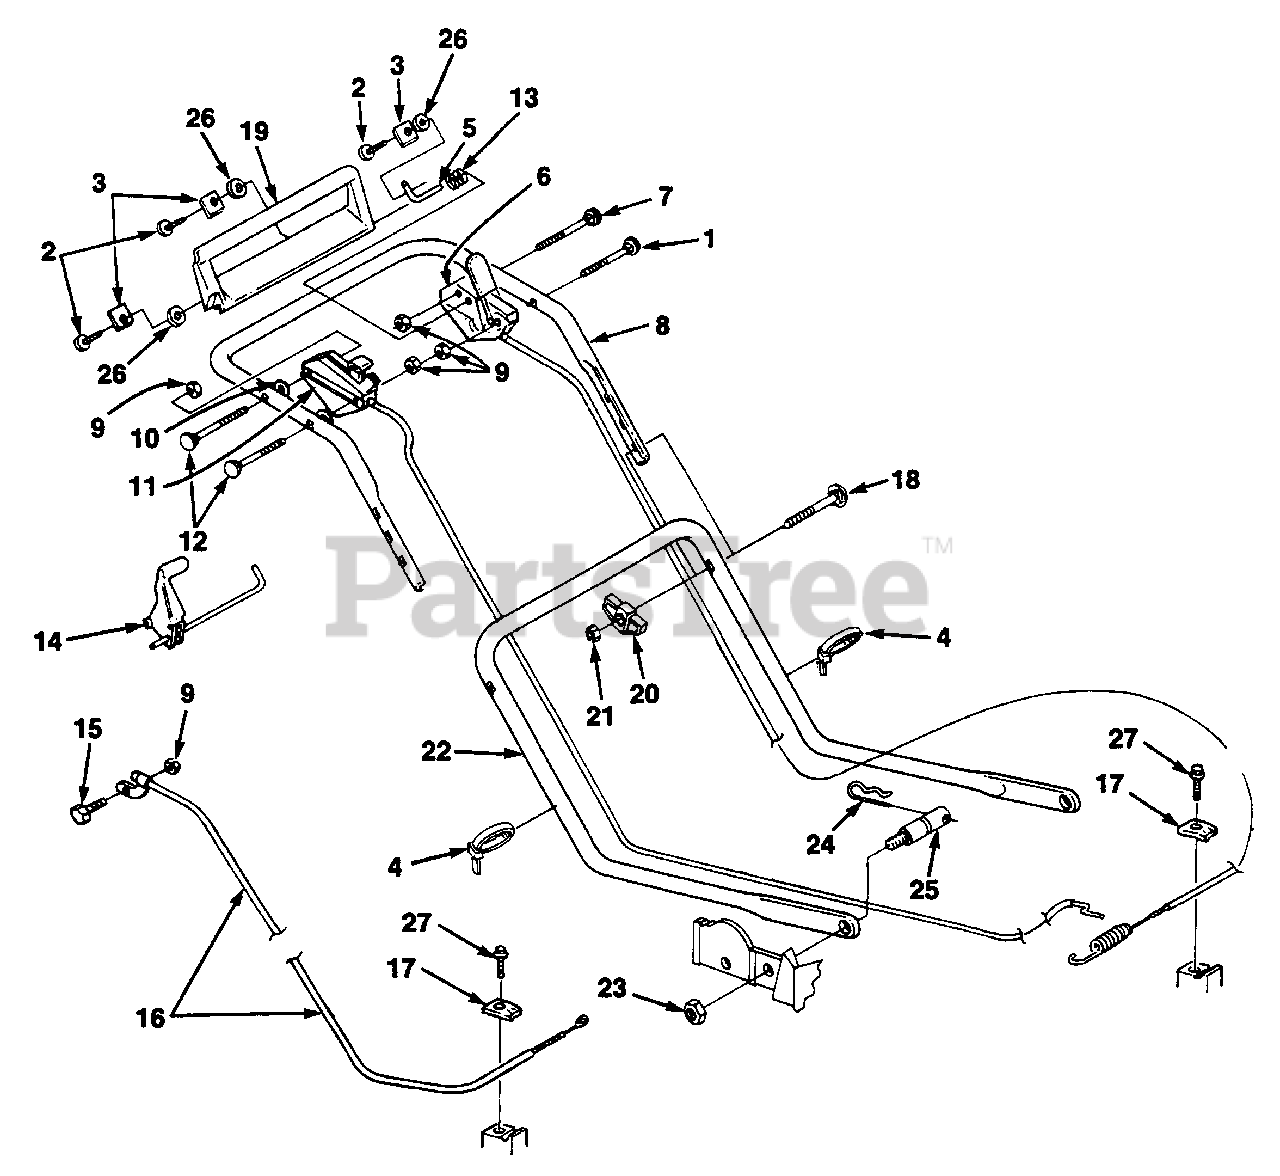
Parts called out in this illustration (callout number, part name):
1	BOLT- Sq. neck
2	SCREW- (1/4-10 x 5/8")
3	CLAMP- Pivot shaft
4	TIES- Cable
5	SHAFT- Pivot
6	CONTROL- Blade/Brake/Clutch
7	BOLT- Sq. neck
8	HANDLE- Upper
9	NUT- Hex (1/4-20)
11	CONTROL- Throttle
12	BOLT- Sq. neck
14	LEVER- Assembly-Traction
15	SCREW- (1/4-20 x 1 1/2")
16	CABLE- Traction
19	BAIL- Brake control
20	KNOB- Handle
21	NUT- Hex (5/16 x 18)
22	HANDLE- Lower
23	NUT- Flange (5/16-18)
24	PIN- Cotter hair
26	WASHER- (1/4")
27	SCREW- (1/4-20 x 5/8")
